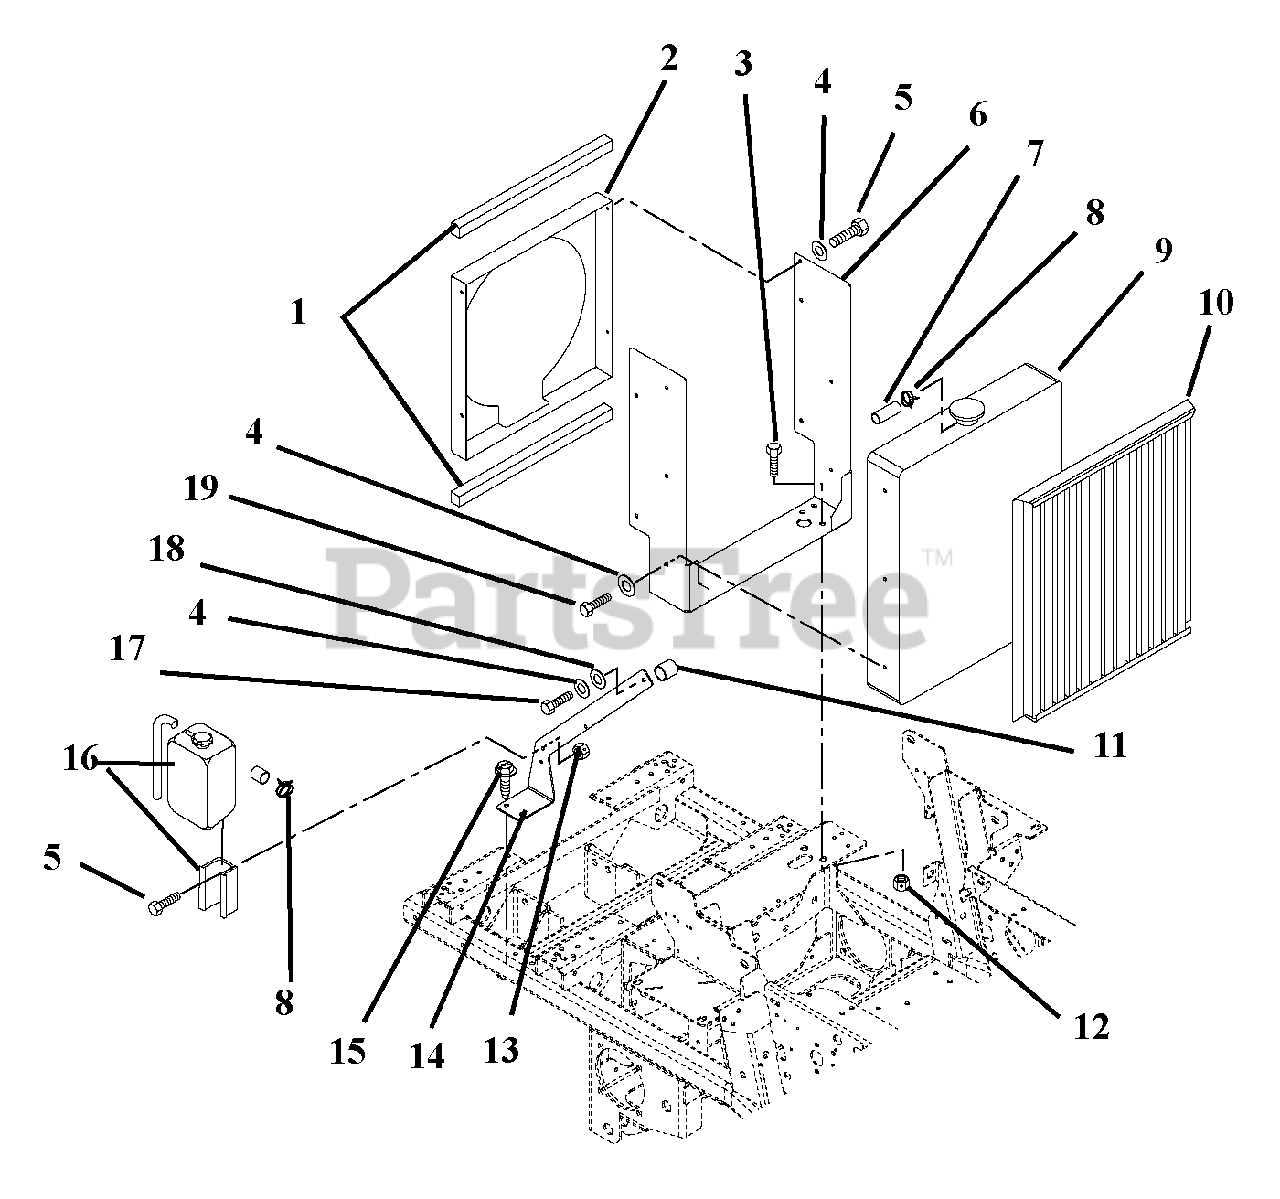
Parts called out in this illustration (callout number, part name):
1	Seal, Trim-LOK Bulk .06 Bubble
2	Weldment, Radiator Shroud
3	Bolt, Hex .38-16 x 1.00 Grade 5
4	Washer, Locking .25 x .062 Regular
5	Bolt, Hex .25-20 x .75 Grade 5
6	Bracket, Radiator Mounting
7	Gas Line, Bulk .25 ID
8	Clamp, Hose Wire .49/.51 x .116
9	Radiator (Comes with the engine)
10	Screen, Radiator
11	Spacer .328 x .76 x 1.01
12	Nut, Locking Top Flange .38-16
13	Nut, Locking Top Flange .25-20
14	Bracket, Overflow Mounting
15	Screw, Tapping .38-16 x .75 Hex Washer Head
16	Reservior Overflow
17	Bolt, Hex M6-1.00 x 45
18	Washer, Flat Steel .281 x .62 x .065
19	Bolt, Hex M6-1 x 16
